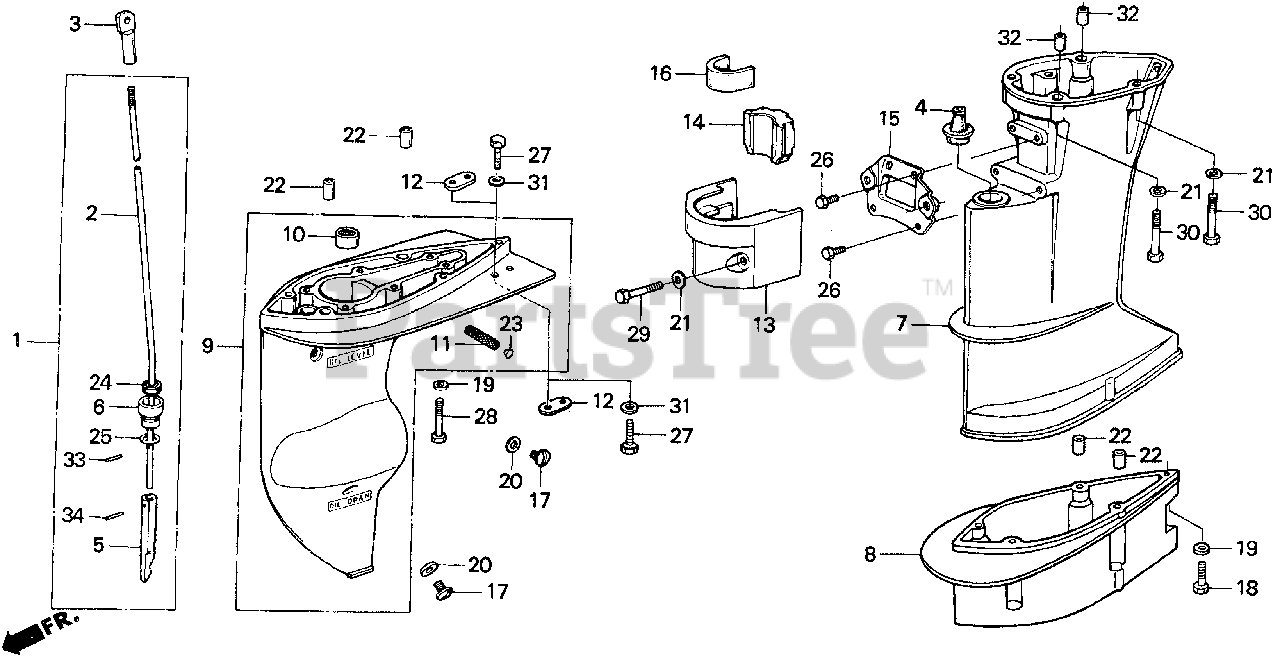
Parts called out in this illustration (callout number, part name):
1	ROD, SHIFT (UL)
2	ROD, SHIFT (UL)
3	JOINT, SHIFT ROD
4	GROMMET, ROD
6	HOLDER, SEAL
7	CASE, EXTENSION *NH282MU* (L) (OYSTER SILVER METALLIC-U)
8	SEPARATOR, EXTENSION *NH282MU* (UL) (OYSTER SILVER METALLIC-U)
9	CASE, GEAR *NH282MU* (OYSTER SILVER METALLIC-U)
10	BEARING, NEEDLE (15X21X16)
11	SCREEN, WATER
12	METAL, ANODE
13	HOUSING, SETTING (LOWER) *NH282MU* (OYSTER SILVER METALLIC-U)
14	RUBBER A, MOUNTING (LOWER)
15	PLATE, SETTING (LOWER)
16	RUBBER B, MOUNTING (LOWER)
17	BOLT, OIL CHECK (8X8)
18	BOLT, HEX. (6X32)
19	WASHER, PLAIN (6MM)
20	WASHER, NYLON (8MM)
21	WASHER, PLAIN (8MM)
22	PIN A, DOWEL (8X10)
23	PLUG, SEALING (10MM)
24	SEAL, WATER (6MM)
25	O-RING (13.8X2.5)
26	BOLT, HEX. (6X12)
27	BOLT, HEX. (6X18)
28	BOLT, HEX. (6X40)
29	BOLT, HEX. (8X40)
30	BOLT, HEX. (8X50)
31	WASHER, PLAIN (6MM)
32	PIN A, DOWEL (10X14)
33	PIN, SPRING (2.5X12)
34	ROLLER (2.5X11.8)
